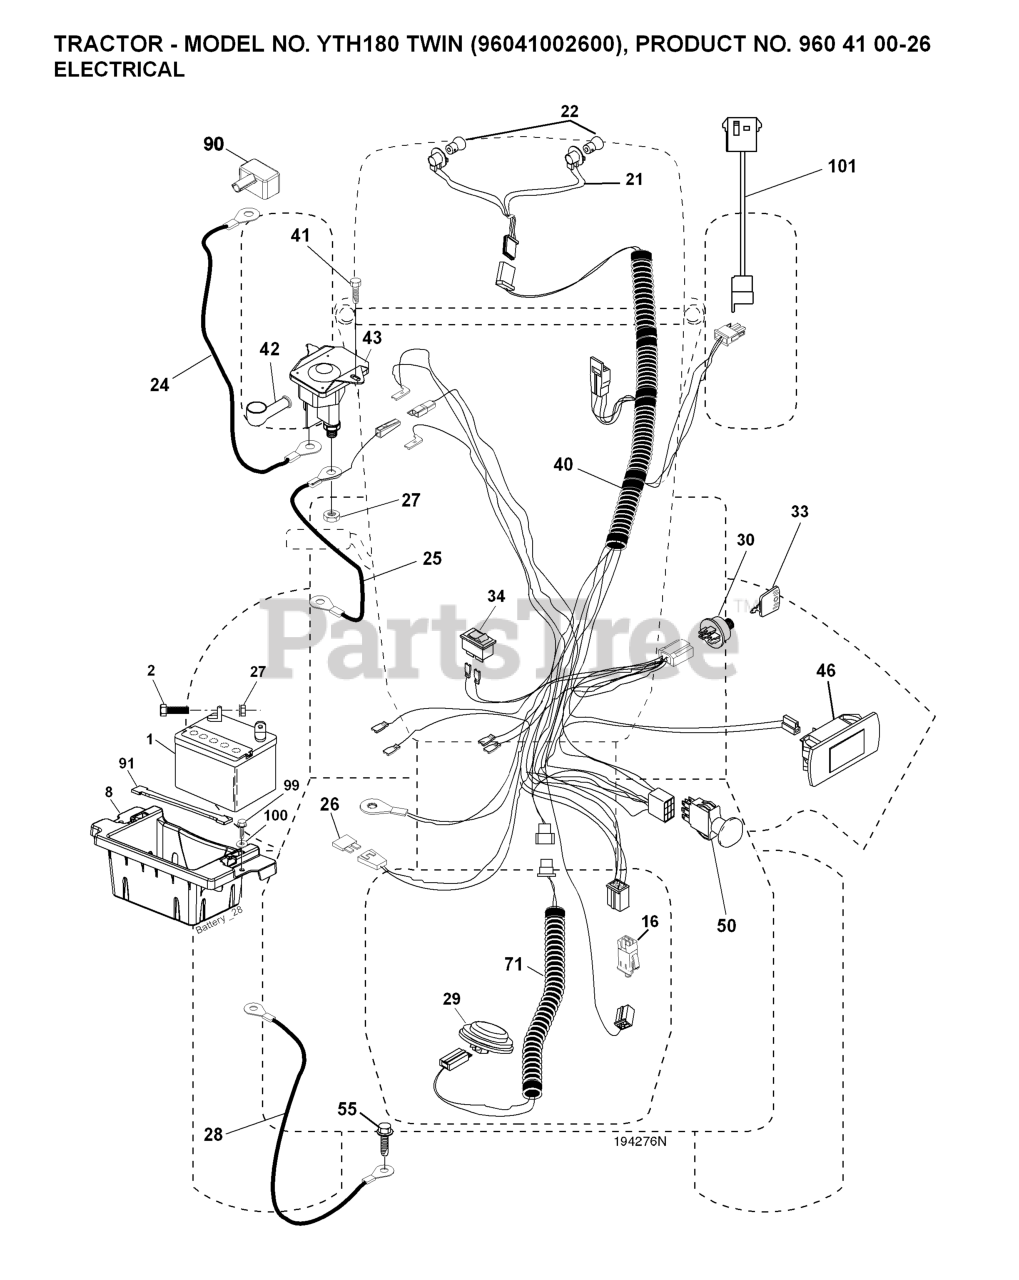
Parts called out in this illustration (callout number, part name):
1	BATTERY 12V .35 AMP
2	BOLT.HEX.1/4.X.3/4.DICHROMATE
8	BOX.BATTERY.MOUNT.FRONT.LT
16	SWITCH INTERLOOK PUSH-IN
21	HARNESS ASSY LIGHT
24	CABLE.BATT.POS.WIRE.TG.DA SOL
25	CABLE.START.RED.17.5".
26	FUSE 20AMP
27	NUT
28	CABLE GROUND 6 GA 21" 90T BLK
29	SWITCH.SEAT.DELTA.OPC.
30	SWITCH.IGN.DELTA.W.LGH.ROS
33	KEY MLD GEN DELTA
40	HARNESS.IGN.DASH.HUQ/P
41	SCREW
42	TERMINAL COVER
43	SOLENOID.W/BRASS.PLUNGER
46	RP.GUAGE.SRVCMNDR.HRMTR.
50	RP.PTO.SWITCH.8 TERMINAL.BLACK
55	SCREW.THDROL.5/16-18X3/4.TTY
71	HARNESS-CHASSIS SUB
90	COVER.TERMINAL.BATTERY
91	STRAP.BATTERY.MOUNT.FRONT(2 2)
99	SCREW HEXWSHR 1/4-20X3/4
101	PIGTAIL.MATNLK.NEW.HAR
